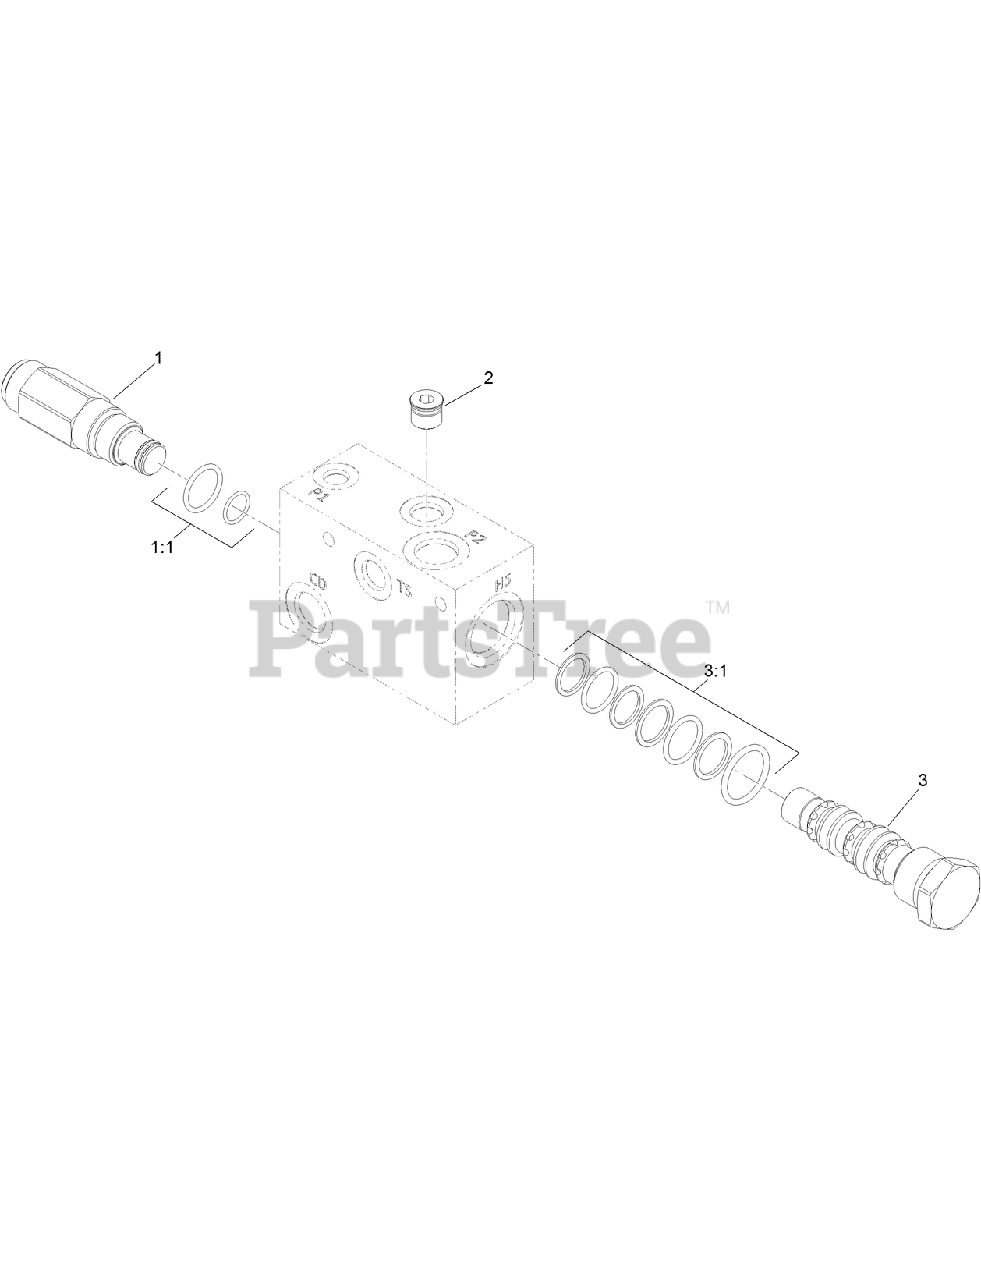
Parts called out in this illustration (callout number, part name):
1	VALVE-CHECK
1:1	SEAL KIT
2	PLUG-HYD
3	VALVE-SHUTTLE, HOT OIL
3:1	SEAL KIT
